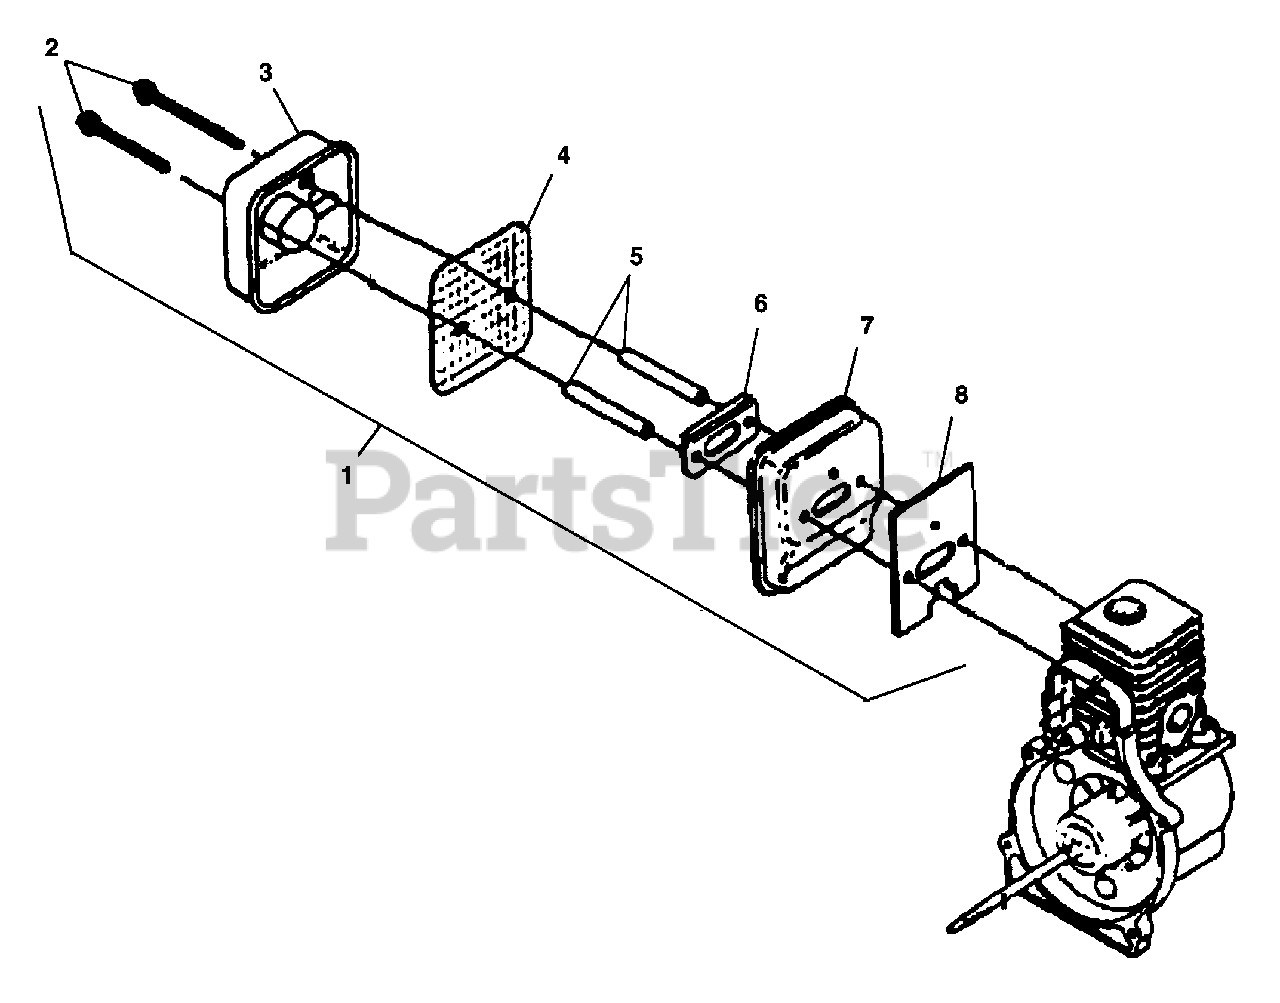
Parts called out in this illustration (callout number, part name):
1	MUFFLER ASSY.
2	SCREW, SEMS HEX HD 10-24 X 2 1/5
3	COVER, MUFFLER
4	SCREEN, SPARK ARRESTOR
5	SPACER, MUFFLER
6	PLATE, MUFFLER SUPPORT
7	BODY, MUFFLER
8	GASKET, MUFFLER
